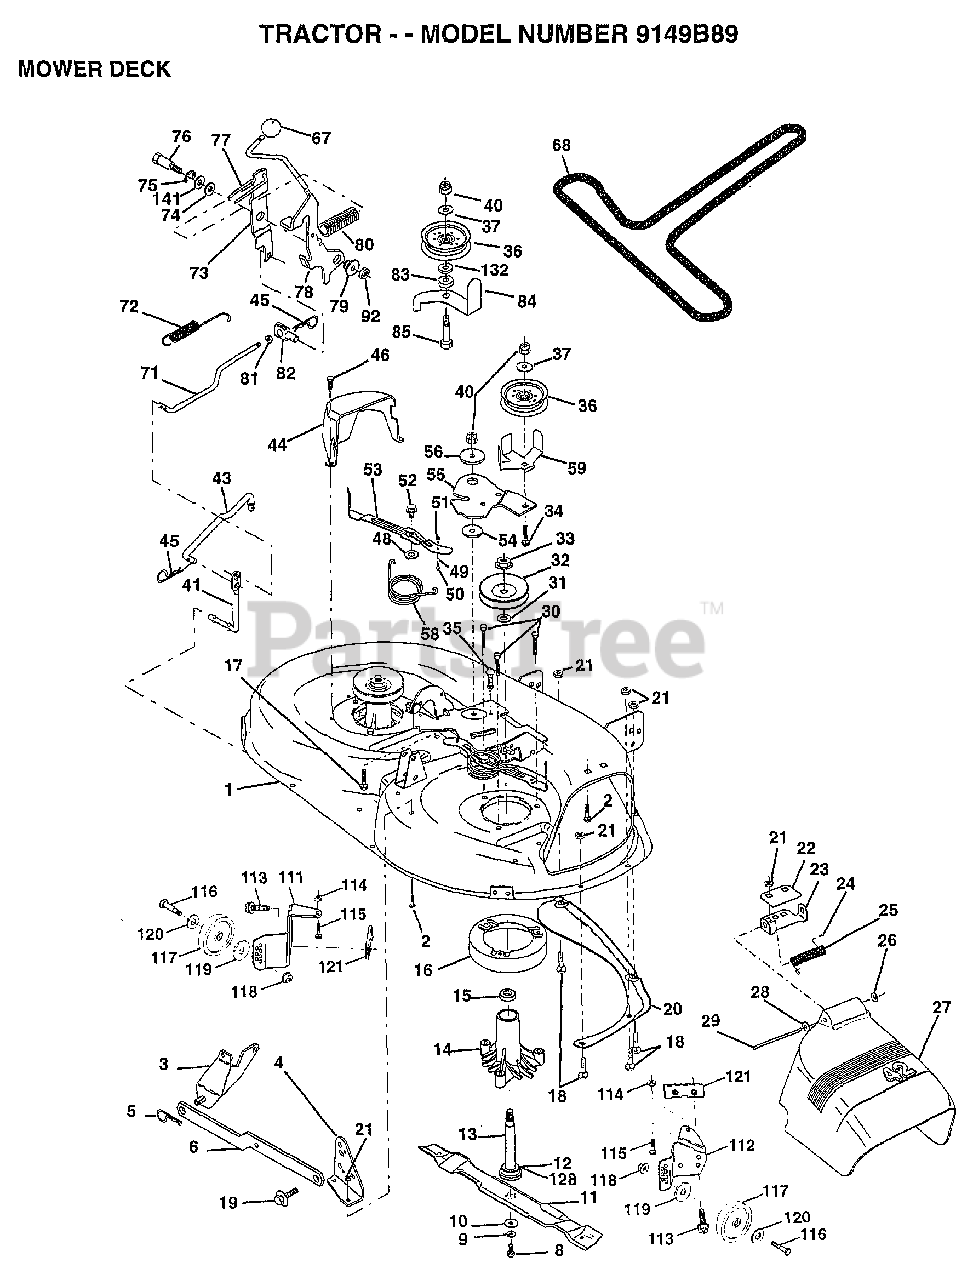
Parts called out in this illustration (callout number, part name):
1	"HOUSING ASSY.42"""
2	BOLT
3	BRKT ASM SWAY BAR
4	BRKT DECK SW BAR
8	BLADE BOLT
10	WASHER.HARD.BLADE
11	"BLADE.42"" MULCHER"
12	BEARING.BALL
14	HSG ASM MANDREL
15	BEARING
16	STRIPPER RND MWR
17	BOLT RDHD 3/8-16
18	BOLT
19	BOLT SHD 5/16-18
20	BAFFLE VORTEX 42
22	STIFFENER BRKT
23	DEFLECTOR BRKT
24	CAP-SLEEVE LT
25	SPRING TORSION
26	NUT PUSH M
27	DEFLECTOR.SHIELD
28	WASHER
29	HINGE ROD
30	"SCREW-THD ROLL,WA"
31	WASHER
32	PULLEY.MANDREL.42
34	BOLT
35	XMAS TREE FASTNER
36	FLAT IDLER PULLEY
37	WASHER
41	PIVOT ROD
43	ROD CLUTCH W/NIBS
44	GUARD MAND LH BLK
45	RETAINER M
46	SCREW.1/4-20X5/8
48	HARD SMALL WASHER
49	ROLLER ASM-CAM
50	SHOULDER BOLT
51	LOCKNUT
52	BOLT.SHLD.5/16-18
53	BRAKE PAD ARM ASM
54	HARDENED WASHER
55	ARM-IDLER
56	SPACER RETAINER
58	SPRING TORSN BRAK
59	GUARD IDLER TUV
67	KNOB.RD.7/16-14
68	BELT.V.T-PATH
71	ROD CLUTCH 38/42
72	RETURN SPRING
73	CLUTCH ARM SECOND
74	WASHER
75	RING
76	SHOULDER BOLT
77	SPRING KEEPER
78	LEVER.ASM.CLUTCH
79	BUSHING
80	SPRING.CLUTCH.MWR
81	NUT
82	TRUNION ADJ
83	WASHER
84	"KEEPER-BELT,FIXED"
85	BOLT
92	NUT
111	BRACKET.GWHL.LH.
112	BRACKET.GWHL.RH.
113	SCREW
116	BOLT M
117	WHEEL.GAGE.BLK.PL
118	LOCKNUT
119	WASHER
120	WASHER
121	BRACKET.EXTRD.GWL
128	WASHER.FELT.
132	WASHER GT
141	WASHER .T
